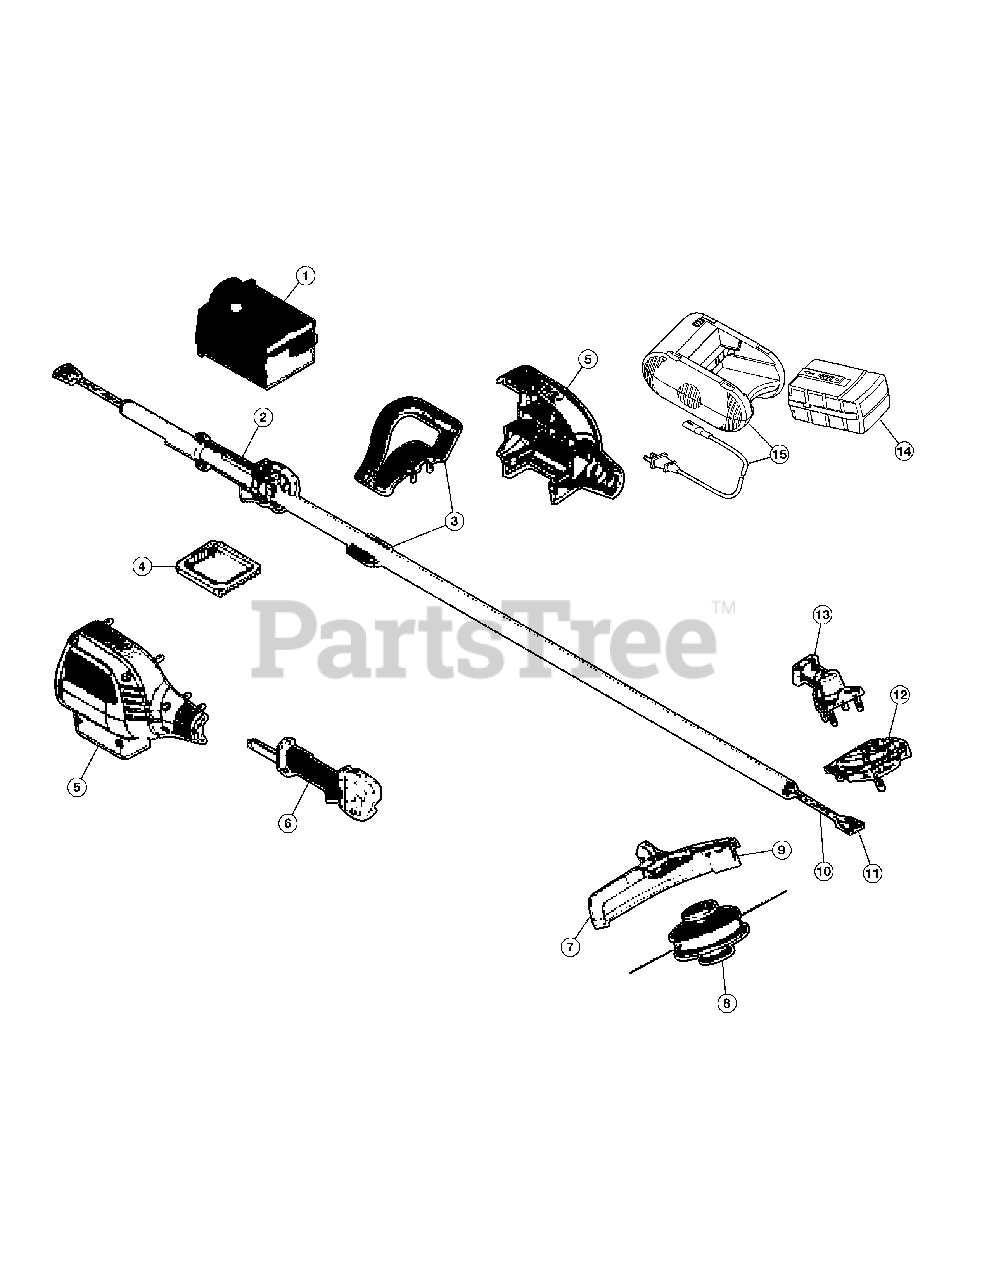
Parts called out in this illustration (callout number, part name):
1	Power Sleeve Assembly
2	Trimmer Shaft Assembly
3	Assist Handle Assembly
4	Controller PCB Assembly
5	Power Housing Assembly
6	Grip Handle Assembly with Switch Wires
7	String Guard Assembly
8	Weedwrap Bumphead
10	Phase Wire Assembly
11	Hall Wire Assembly
12	Motor Assembly
14	Battery 18.5 V
15	Charger 21 V
